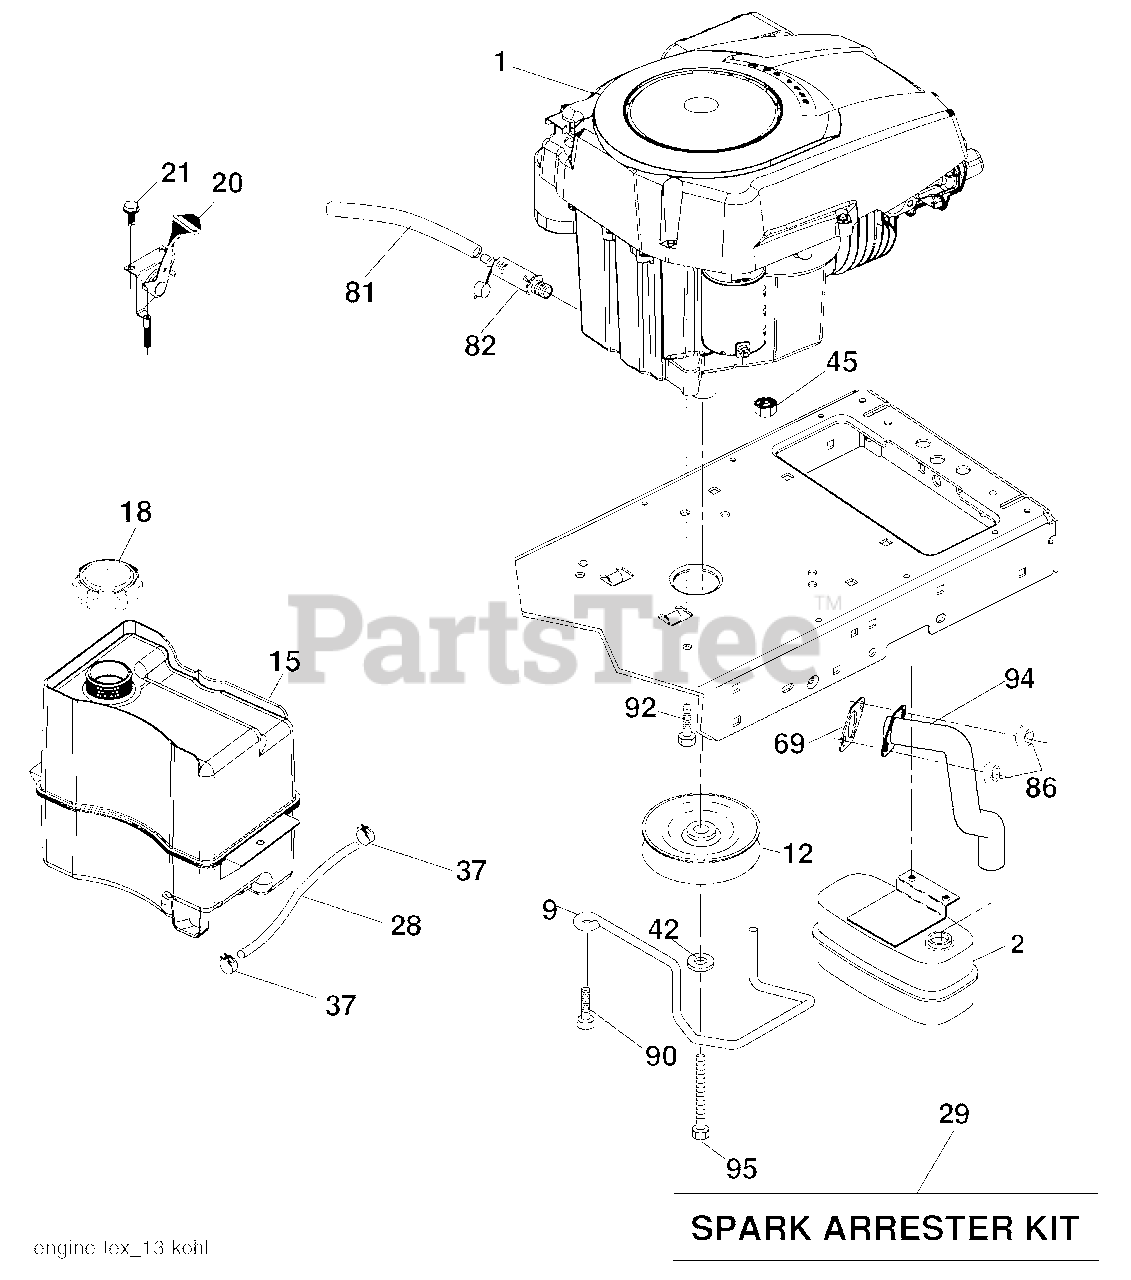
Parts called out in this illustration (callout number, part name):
2	Muffler
9	Keeper Belt Engine
12	Pulley Engine
15	Tank Fuel
18	Cap Asm
20	Control Throttle
21	Screw 10 x 3/4 Single Lead-Hex
28	Fuel Line
29	Spark Arrester Kit
37	Clamp Hose
42	Washer Lock 7/16
45	Nut Keps Hex 1/4-20 unc
62	Shield Heat Muffl er
69	Gasket
81	Tube Drain Oil Easy
82	Plug Drain Oil
86	Nut
90	Screw 3/8-16 x 1
92	Screw 3/8-16 x 1
94	Tube Exhaust
95	Bolt Hex 7/16-20 x 4 x 5 Ga.-1.5
